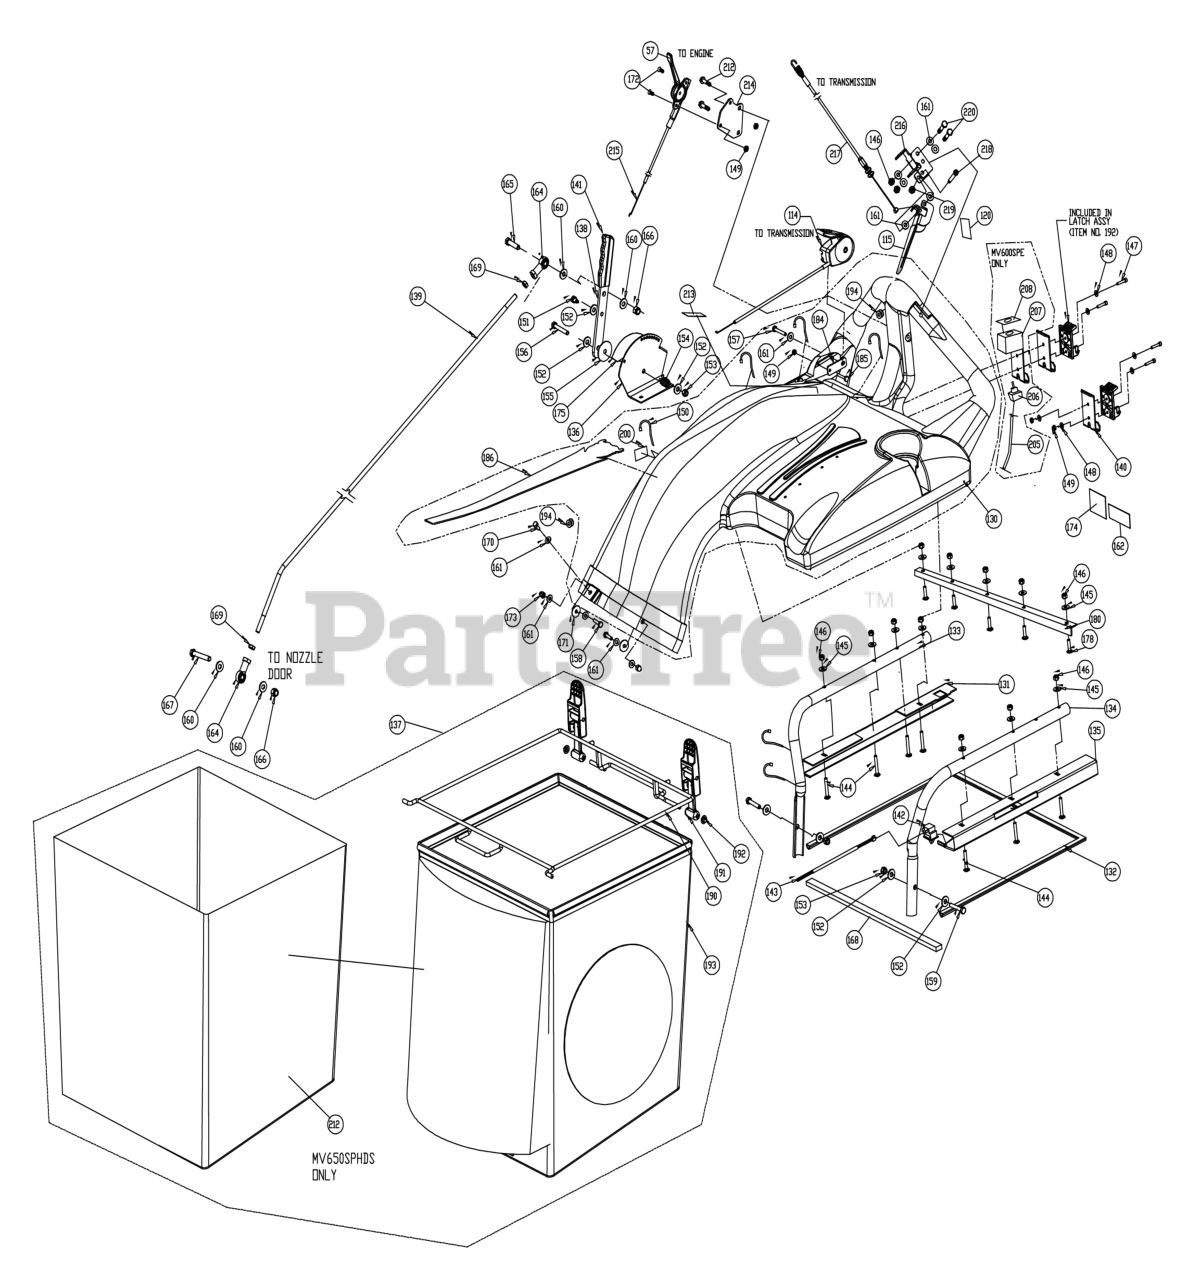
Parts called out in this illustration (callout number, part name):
57	CONTROL THROTTLE BLOWER
114	CABLE CONTROL SHIFT
115	HANDLE, MV CLUTCH CABLE
120	LABEL CLUTCH DRIVE
130	HOOD ASSY W/LABEL MV
131	BRACKET BAG CHANNEL RH W/SEAL MV VAC
132	SEAL 60" STRIP
133	HANDLE BRACE LID RH SP VAC
134	HANDLE BRACE LID LH SP VAC
135	BRACKET, BAG CHANNEL LH
136	BRACKET NOZZLE DOOR ADJ W.LABEL MV VAC
137	BAG W/ FRAME AND LATCHES (SEE ACCESSORY PRICELIST)
138	BAR LIFT NOZZLE DOOR W/GRIP MV VAC
139	ROD LIFT NOZZLE DOOR
140	PLATE BAG LATCH
141	GRIP LEVER 1" X 4.25"
142	SWITCH INTERLOCK
143	WIRE HARNESS, MV BAG SWITCH
144	BOLT CARRIAGE 1/4-20 X 1 3/4 Z/P
145	WASHER 1/4" FLAT Z/P
146	NUT LOCK 1/4"-20 HEX Z/P
147	SCREWCAP SOCKET HEAD #10-24 X 1"
148	WASHER #10SAE 7/32"X1/2"X1/16"
149	NUT LOCK LT #10-24 HEX
151	PIN-SCREW
152	WASHER 5/16" FLATWASHER Z/P
153	NUT LOCK 5/16"-18 HEX Z/P
154	SPRING LEVER GZ
155	WASHER FIBRE
156	SCREWCAP 5/16"-18X2" HCS ZP
157	SCREWCAP 1/4"-20X2 1/4" HCS ZP
158	SCREWCAP 1/4"-20 X 1" HCS ZP
159	SCREWCAP 5/16"-18X1 3/4" HCS ZP
160	WASHER 3/8"FC7/16"X1"X5/64"
161	WASHER 1/4"SAE9/32"X5/8"X1/16"
162	LABEL SAFETY PROTECT READ MANUAL
164	ROD END BALL JOINT 3/8" NF
165	SCREWCAP 3/8" - 16 X 1/2" HCS ZP
166	NUT LOCK 3/8"-16 HEX
167	SCREWCAP 3/8"-16X2 1/2" HCS ZP
168	SEAL 20.5" STRIP
169	NUT 3/8"-24 FIN HEX Z/P
170	SCREWCAP 1/4"-20X3/4" HCS ZP
171	WASHER FLAT FENDER 1/4"
172	SCREW MACHINE FLAT HD PHIL #10-24
173	NUT ACORN 1/4-20 HIGH CROWN
174	LABEL DANGER FLYING DEBRIS
175	LABEL NOZZLE DOOR MV VAC
178	BOLT CARRIAGE 1/4" X 3/4"
180	BRACKET HOOD FRONT STRAIGHTENER
184	PLATE SHIFT CONTROL ANTI ROTATE
185	SCREWCAP #10-24 X 1 1/4" HWF ZP
186	LABEL HOOD DECAL
190	ROD BAG WA
191	LATCH ASSY W/NUT MV VAC
192	NUT PAL 5/16
193	BAG MV STANDARD (SEE ACCESSORY PRICELIST)
194	GROMMET RUBBER 5/8" OD X 3/8" ID
213	LABEL THROTTLE BC
214	PLATE, MV THROTTLE CONTROL
215	CABLE, THROTTLE CONTROL 53.50" H
216	MV CABLE MOUNT WA
217	KIT, MV DRIVE CABLE W/GREASE
218	BOLT SHOULDER 1/4" X 1 3/4"
219	NUT #10-24 HEX NUT
220	SCREWCAP 1/4"-20X1 3/4" HCS ZP
221	SCREW PLASTITE 1/4-10 X 3/4 HWH ZP
